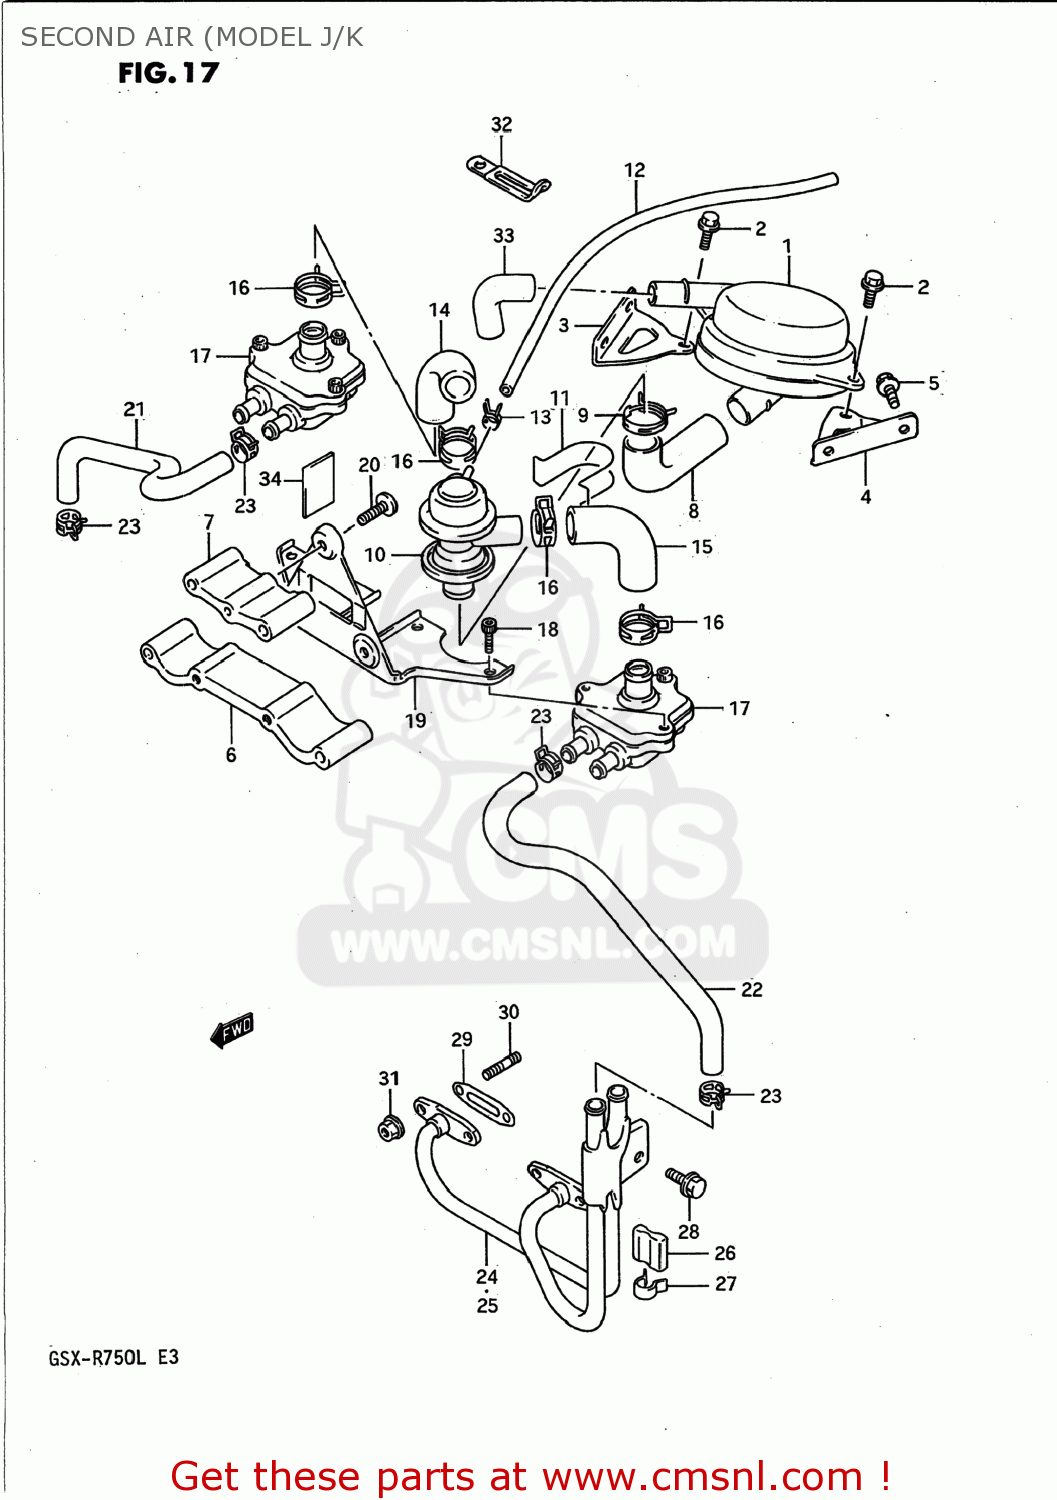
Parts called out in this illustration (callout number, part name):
1	CLEANER ASSEMBLY,SECOND AIR
2	BOLT
3	BRACKET,SECOND AIR CLEANER
4	BRACKET,SECOND AIR CLEANER
5	BOLT
6	SPACER
7	SPACER
8	(CA) HOSE,SECOND AIR NO.3
9	CLIP
10	VALVE ASSEMBLY,AIR SWITCH
11	CLAMP,SWITCHING VALVE
12	HOSE
13	CLAMP
14	HOSE,SECOND AIR NO.2,RIGHT
15	(CA) HOSE,SECOND AIR NO.2
16	CLIP
17	VALVE ASSY,2ND AIR REED
18	BOLT
19	BRACKET,AIR VALVE
20	SCREW
21	(CA) HOSE,SECOND AIR NO.1
22	(CA) HOSE,SECOND AIR NO.1
23	CLIP
24	PIPE ASSEMBLY,SECOND AIR
25	(CA) PIPE,SECOND AIR,LEFT
26	(CA) CUSHION
27	(CA) CLIP,SECOND AIR PIPE
28	BOLT 6X12
29	GASKET,SECOND AIR PIPE (NAS)
30	STUD BOLT
31	NUT 6MM
32	CLAMP L:35
33	(CA) HOSE,SECOND AIR CLEANER
34	CUSHION
